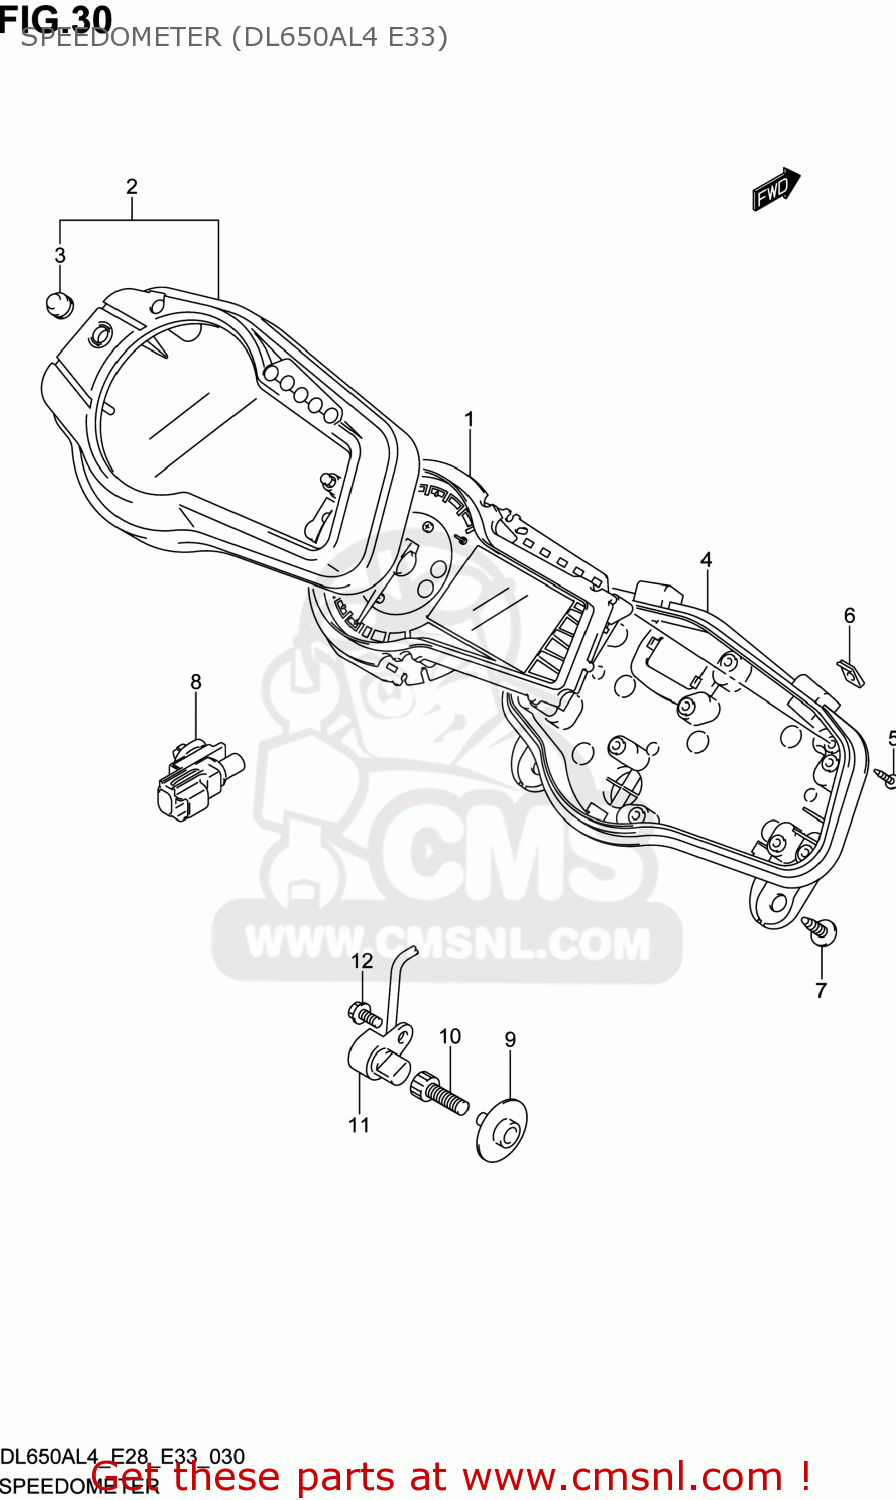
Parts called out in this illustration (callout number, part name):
1	SPEEDOMETER
2	CASE ASSY,UPR
3	RUBBER,SWITCH
4	CASE ASSY,LWR
5	SCREW(3X16)
6	NUT
7	SCREW
8	SENSOR,AIR TEMP
9	ROTOR,SPEED
10	BOLT
11	SENSOR,SPEED
12	BOLT
